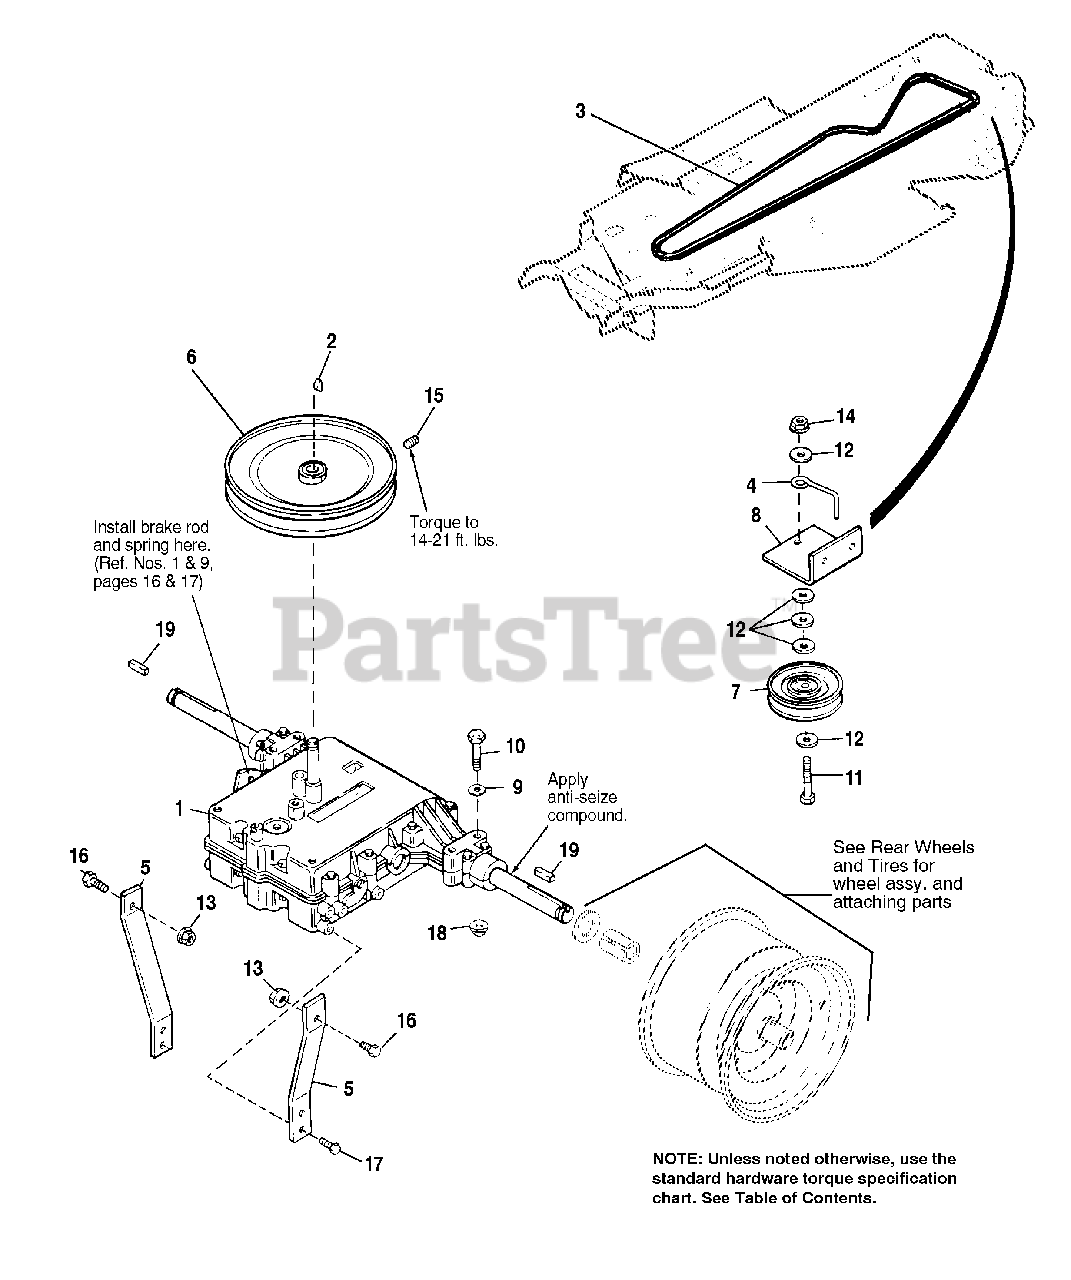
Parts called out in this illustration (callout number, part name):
1	TRANSMISSION, 5-Speed, Peerless
2	KEY
4	BELT STOP
5	SUPPORT, Transmission
6	PULLEY ASSY., Driven
7	PULLEY, "V"
8	BRACKET, Pulley
9	WASHER, Plain, 5/16
10	CAPSCREW, Hex Hd., 5/16-18 x 2-1/2
11	CAPSCREW, Hex, 3/8-16 x 1-3/4
12	WASHER, Plain, 3/8
13	NUT, Hex, Flange, 5/16-18
14	NUT, Flange, Whizlock, 3/8-16
15	SETSCREW, 5/16-18 x 1/2
16	SCREW, Whiz, 5/16-18 x 3/4
17	SCREW, Taptite, 5/16-18 x 5/8
18	NUT, Flange, Lock, 5/16-18
19	KEY, 3/16 Sq. x 1-1/2
